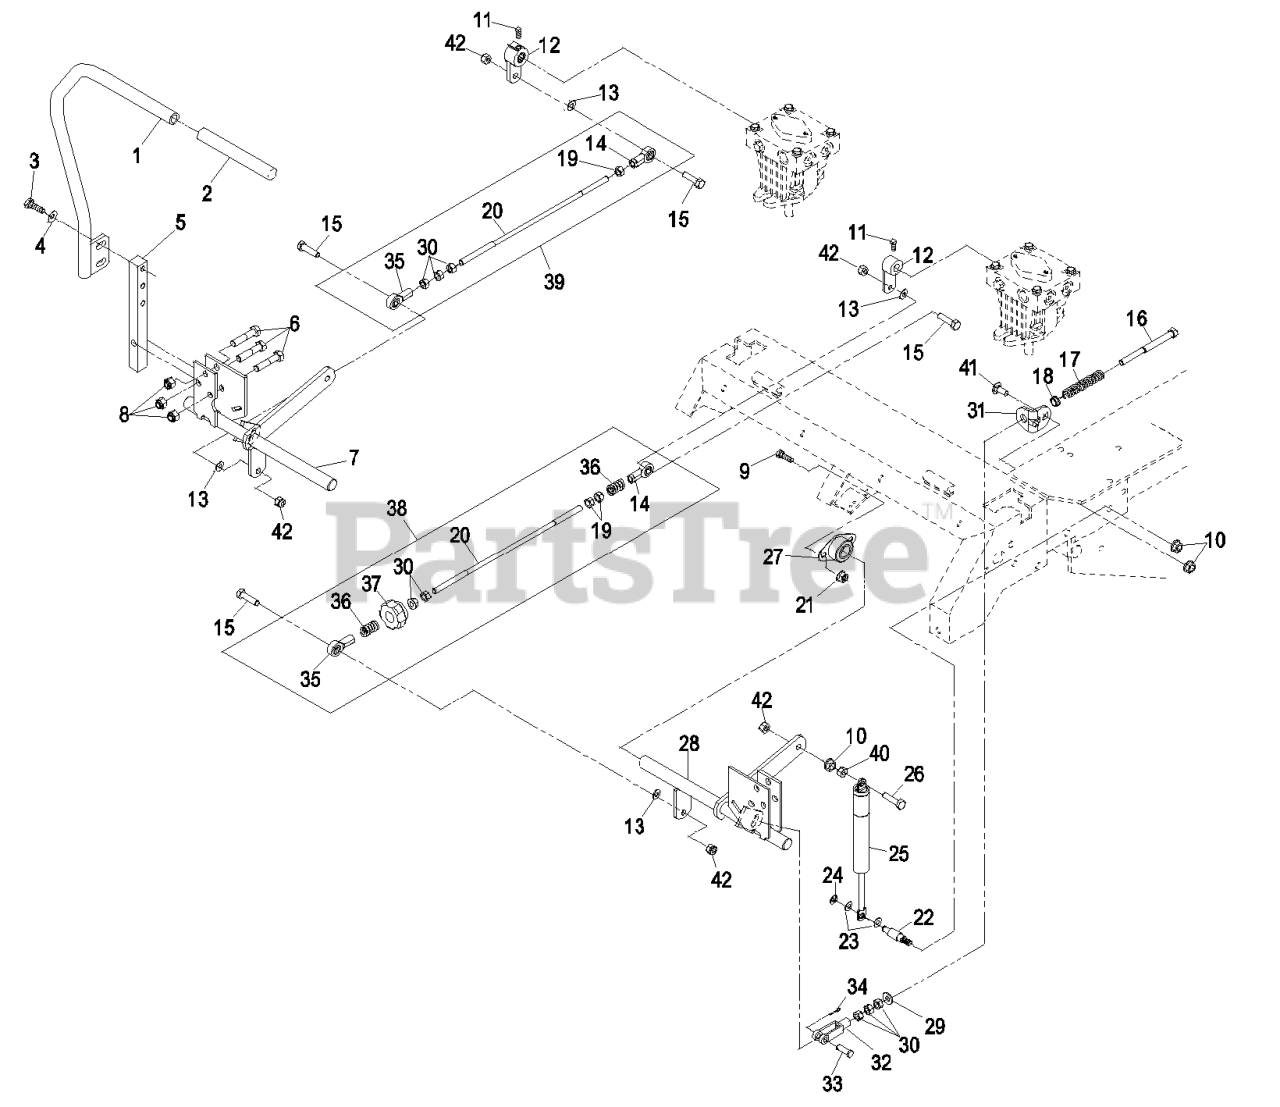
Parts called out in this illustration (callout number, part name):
1	ASM.RH LEVER/GRIP
2	GRIP,CONTROL LEVER
3	SCREW-HH
4	WASHER-BELLEVILLE
5	ARM-SHAFT, CONTROL
6	SCREW-HH
8	NUT-LOCK, NI
9	SCREW-HH
11	SCREW-SET
12	ARM-CONTROL
13	WASHER-FLAT
14	BALLJOINT-LH
15	SCREW-HH
16	BOLT-RETURN, NEUTRAL
17	SPRING-RETURN, NEUTRAL
18	BUSHING-NYLON, FLANGED
19	NUT
20	LINK-ROD, TRACKING
21	NUT-HHF, WHIZ
22	PIN-DAMPER
23	WASHER-PLAIN
24	RING-RETAINING, EXT
25	DAMPER-CONTROL, MOTION
26	SCREW-HH
27	BEARING-FLANGE, SIDE
28	CONTROL-MOTION, LH
29	WASHER-FLAT
30	NUT-HEX
31	TAB-ADJUSTMENT
32	YOKE-ADJUSTABLE
33	PIN-CLEVIS
34	PIN-COTTER
35	BALLJOINT-RH
36	SPRING-COMPRESSION
37	KNOB-TRACKING
38	TRACKING ROD ASM
39	TRACKING ASM
40	NUT-HEX
41	SCREW-CARR
42	NUT-LOCK, NI
